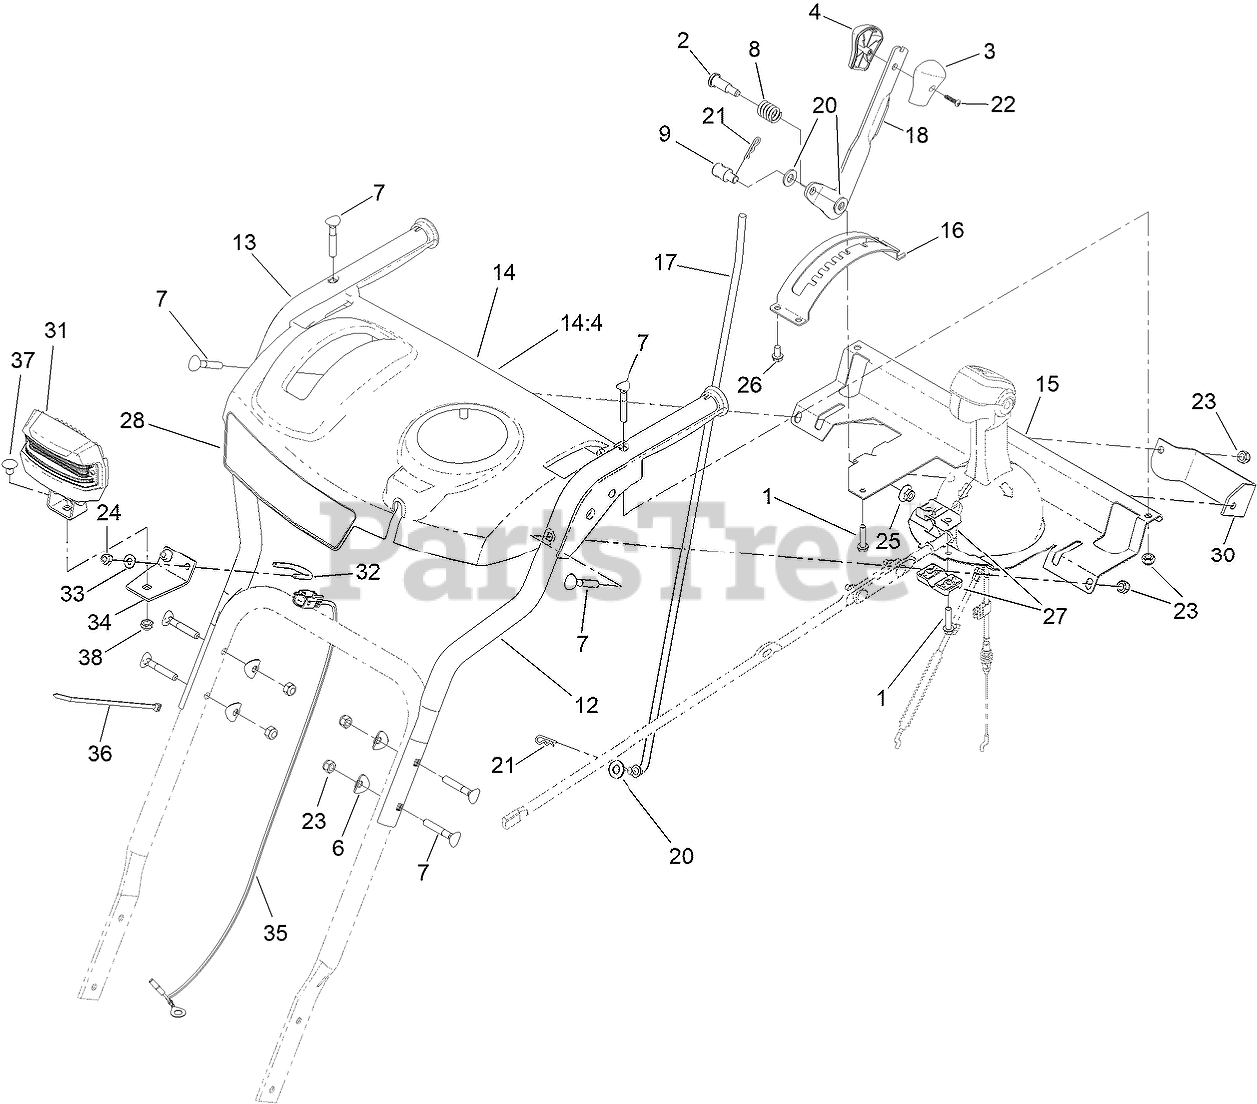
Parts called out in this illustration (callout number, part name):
1	SCREW-PLASTIC,HWH
2	SCREW-SHOULDER, HH
3	KNOB-SHIFT, LH
4	KNOB-SHIFT, RH
6	WASHER-CUP
7	SCREW-HANDLE
8	SPRING-COMPRESSION
9	TRUNNION-ROD
12	HANDLE-UPPER, LH
13	HANDLE-UPPER, RH
14	CONTROL PANEL ASM
14:4	DECAL-SAFETY
15	SUPPORT-PANEL, CONTROL
16	MOUNT-SELECTOR, SPEED
17	ROD-SELECTOR, GEAR
18	SELECTOR-SPEED
20	WASHER-THRUST
21	PIN-HAIR
22	SCREW-PPH
23	NUT-HEX
24	NUT-HEX
25	NUT-HF
26	SCREW-PLASTITE
27	SUPPORT-ROD
28	DECAL-CONSOLE
30	PLATE-SUPPORT, SHIFT
31	LED LIGHT ASM
32	CLAMP-LIGHT
33	WASHER-PLAIN
34	BRACKET-LIGHT
35	HARNESS-WIRE
36	TIE-CABLE
37	BOLT-CARR
38	NUT-HEX
